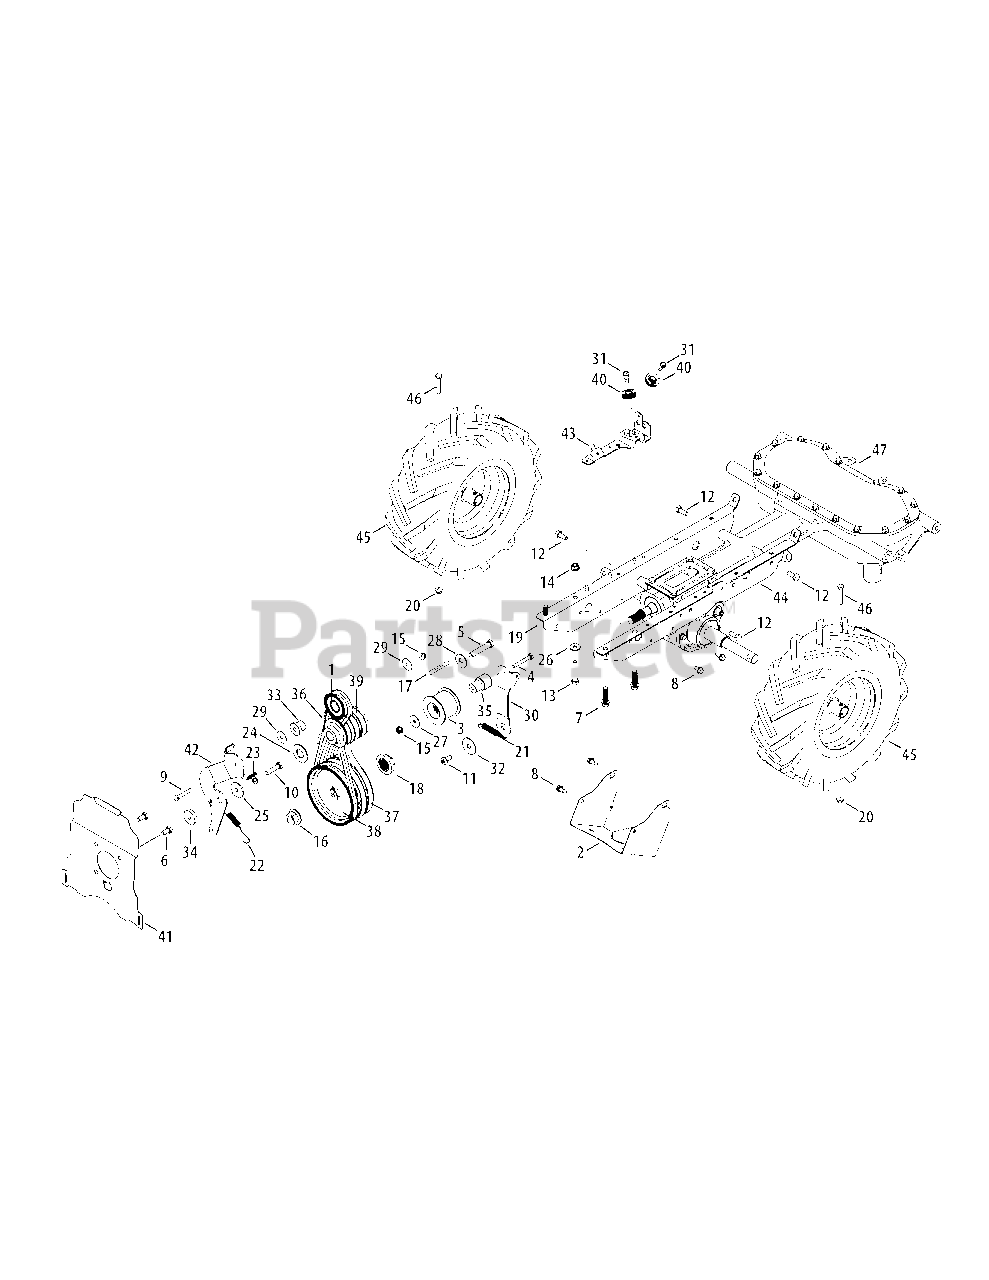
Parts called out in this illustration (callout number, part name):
1	Idler Pulley Assembly, 1.917 OD
2	Pulley Shield Assembly
3	Idler Pulley Assembly
4	Hex Cap Screw, 1/4-20 x 1.75
5	Hex Head Screw, 3/8-24 x 2.00
6	Hex Head Screw, 5/16-24 x .625
7	Screw, 3/8-16 x 1.250
8	Screw, 1/4-20 x 0.500
9	Hex Head Screw, 1/4-20 x 1.50
10	Hex Head Screw, 5/16-24 x 1.25
11	Machine Screw, 5/16-18 x 0.750
12	Hex Head Screw, 5/16-18 x .75, Patch
13	Hex Cap Screw, 5/16-18 x 1.75
14	Flangelock Nut, 5/16-18, B&S
15	Flangelock Nut, 1/4-20
16	Flange Nut, 9/16-18
17	Square Key, 3/16 x 2.00
18	Pulley Hub, 5/8 SPLINE
19	RH Mount Frame
20	Flangelock Nut, 1/4-20
21	Extension Spring, .429 OD x 2.515
22	Extension Spring, LT5 PTO
23	Washer, Lock, 5/16
24	Washer, Flat, .760 x 1.50 x .120
25	Washer, Flat, .330 x 1.25 x .120
26	Washer, .396 x 1.140 x .095, B&S
27	Falt Washer, .255 x 1.00 x .060
28	Washer, Bell, .396 x 1.140 x .095
29	Washer, Flat, .265 x 1.0 x .030
30	Forward Idler Bracket
31	Screw, Shoulder, 1/4-28 x .342 x .335
32	Forward Idler Pivot Spacer
33	Spacer, Shoulder, .260 x .785 x .538
34	Reverse Idler Pivot Spacer
35	Idler Spacer
36	V Belt, 3L x 29.125 LG
37	V Belt, 4L x 25.4 LG
38	Transmission Pulley
39	Engine Pulley, 3L & 4L
40	Cable Roller
41	Cover Mounting Plate
42	Reverse Idler Bracket
43	Pulley Mounting Bracket
44	LH Mount Frame
45	Wheel Assembly, 13 x 5 x 6
45	Rim Only, Beige
46	Hex Head Screw, 1/4-20 x 1.5
47	Transmission Assembly
